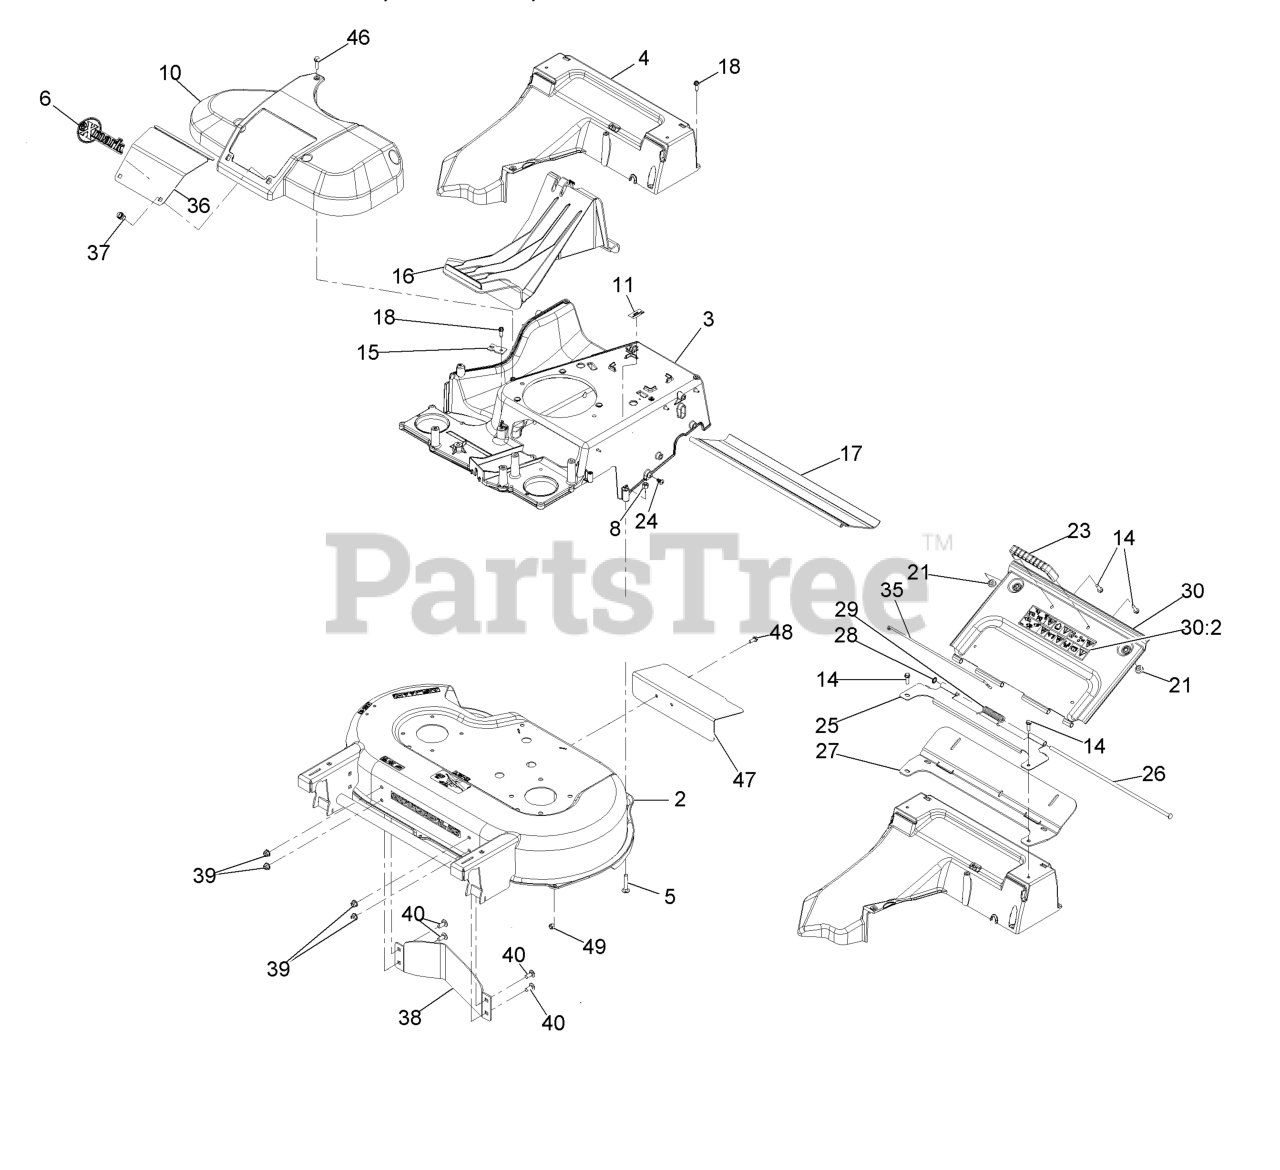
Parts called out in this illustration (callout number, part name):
2	Deck-30, W/Decals
3	Frame
5	Bolt-Carriage 5/16-18 X 1 3/4
6	Decal-Exmark Logo
8	Nut-Nyloc 5/16-18
10	Cover-Belt
11	Decal-Patent
14	Screw-HWH 1/4-10 X .82 Plastite
15	Bracket-Cable, Traction
16	Plug-Mulch
17	Shield-Trailing
18	Screw-HWH 1/4-20 X 3/4 Tf
23	Handle-Door
24	Screw-PTH
25	Bracket-Hinge
26	Pin-Hinge
27	Seal-Door
28	Ring-Retaining
29	Spring-Torsion, Cover
30	Rear Door ASM
30:2	Decal-Warning
35	Clip-Seal
36	Door-Access
37	Fastener
38	Baffle-Control
39	Nut-Nyloc 5/16-18 Flg
40	Screw-Button Head 5/16-18 X 3/4
46	Screw-HWH 1/4-20 X 1 Tf
47	Deflector-Rear, 30" Deck
48	Screw-HWH
49	Nut-Nyloc 1/4-20
99	Frame Plate Kit
99:1	Plate-Frame
99:2	Bolt-Carriage 1/4-20 X 1 1/4
99:3	Nut-Nyloc 1/4-20
